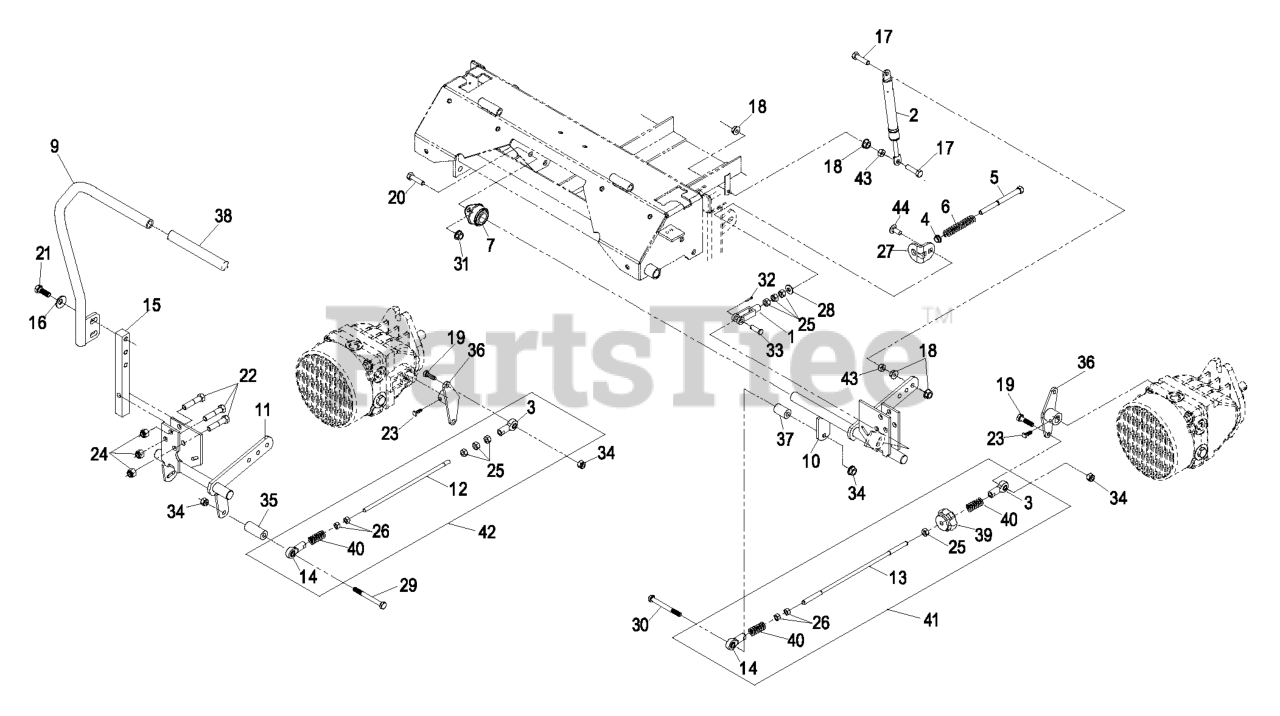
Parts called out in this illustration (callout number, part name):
1	YOKE-ADJUSTABLE
2	DAMPER-CONTROL, MOTION
3	BALLJOINT-RH
4	BUSHING-NYLON, FLANGED
5	BOLT-RETURN, NEUTRAL
6	SPRING-RETURN, NEUTRAL
7	BEARING-FLANGE, SIDE
9	ASM.RH LEVER/GRIP
11	CONTROL-MOTION, RH
12	LINK,XP HYDRO CONNECT RH
13	LINK,TRACKING ROD XP
14	BALLJOINT-LH
15	ARM-SHAFT, CONTROL
16	WASHER-BELLEVILLE
17	SCREW-HH
19	SCREW-HH
20	SCREW-HH
21	SCREW-HH
22	SCREW-HH
23	SCREW-SET
24	NUT-LOCK, NI
25	NUT-HEX
27	TAB-ADJUSTMENT
28	WASHER-FLAT
29	SCREW-HH
30	SCREW-HH
31	NUT-HHF, WHIZ
32	PIN-COTTER
33	PIN-CLEVIS
34	NUT-LOCK, NI
35	SPACER-CONTROL, HYD
36	ARM-CONTROL, HYDRO
37	SPACER-HYDRO CONTROL, LH
38	GRIP,CONTROL LEVER
39	KNOB-TRACKING
40	SPRING-COMPRESSION
41	TRACKING ROD ASM
42	RH HYD CONNECT LINK ASM
43	NUT-HEX
44	SCREW-CARR
